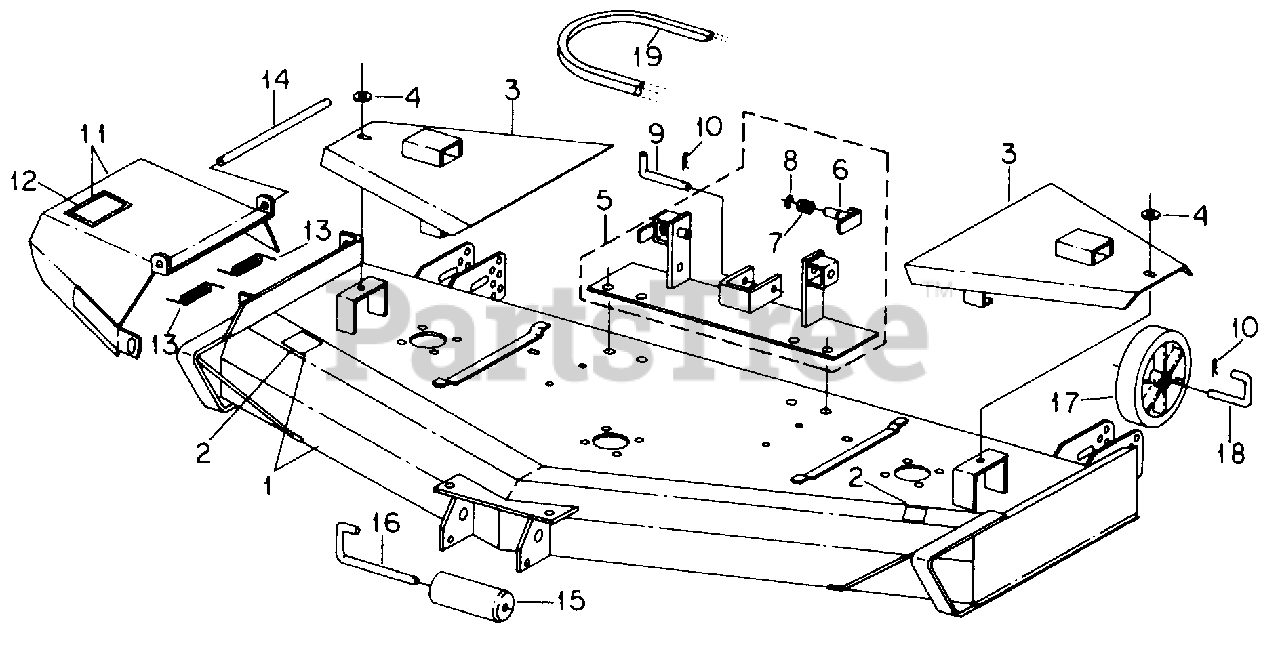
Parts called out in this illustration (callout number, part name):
1	Housing w/Product Graphics
2	Product Graphic, Danger
3	Cover, V-Belt
4	Washer, .406 X 1.500 X .054
5	Bracket Assy, Rear Mtg
8	Ring, Snap
11	Shield w/Product Graphic, Deflector
12	Product Graphic, Danger
14	Rod, Deflector
15	Roller, Front
16	Pin, Roller
17	Wheel, Gauge 8 In.
18	Pin, Gauge Wheel
19	Belt, Spindle Drive
